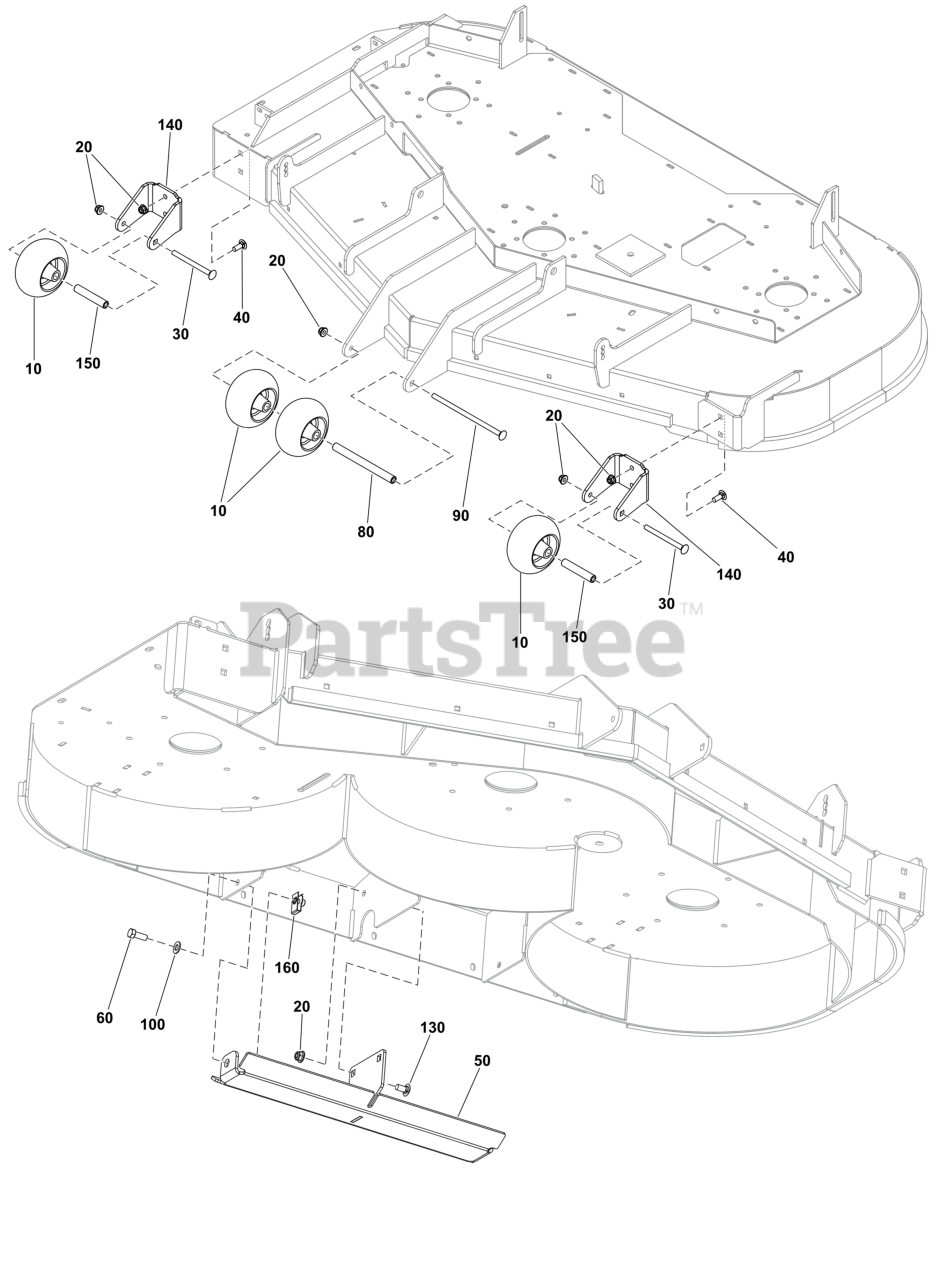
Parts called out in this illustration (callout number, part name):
20	NUT, 3/8-16 HEX NYLOCK
40	BOLT, RD HD, 3/8-16X1
50	PLATE, Skid
60	BOLT, 3/8-16 X 1" GD5
90	BOLT, Carriage 3/8-16 X 8
130	BOLT, 3/8-16X.75 G5
140	MOUNT, Roller
